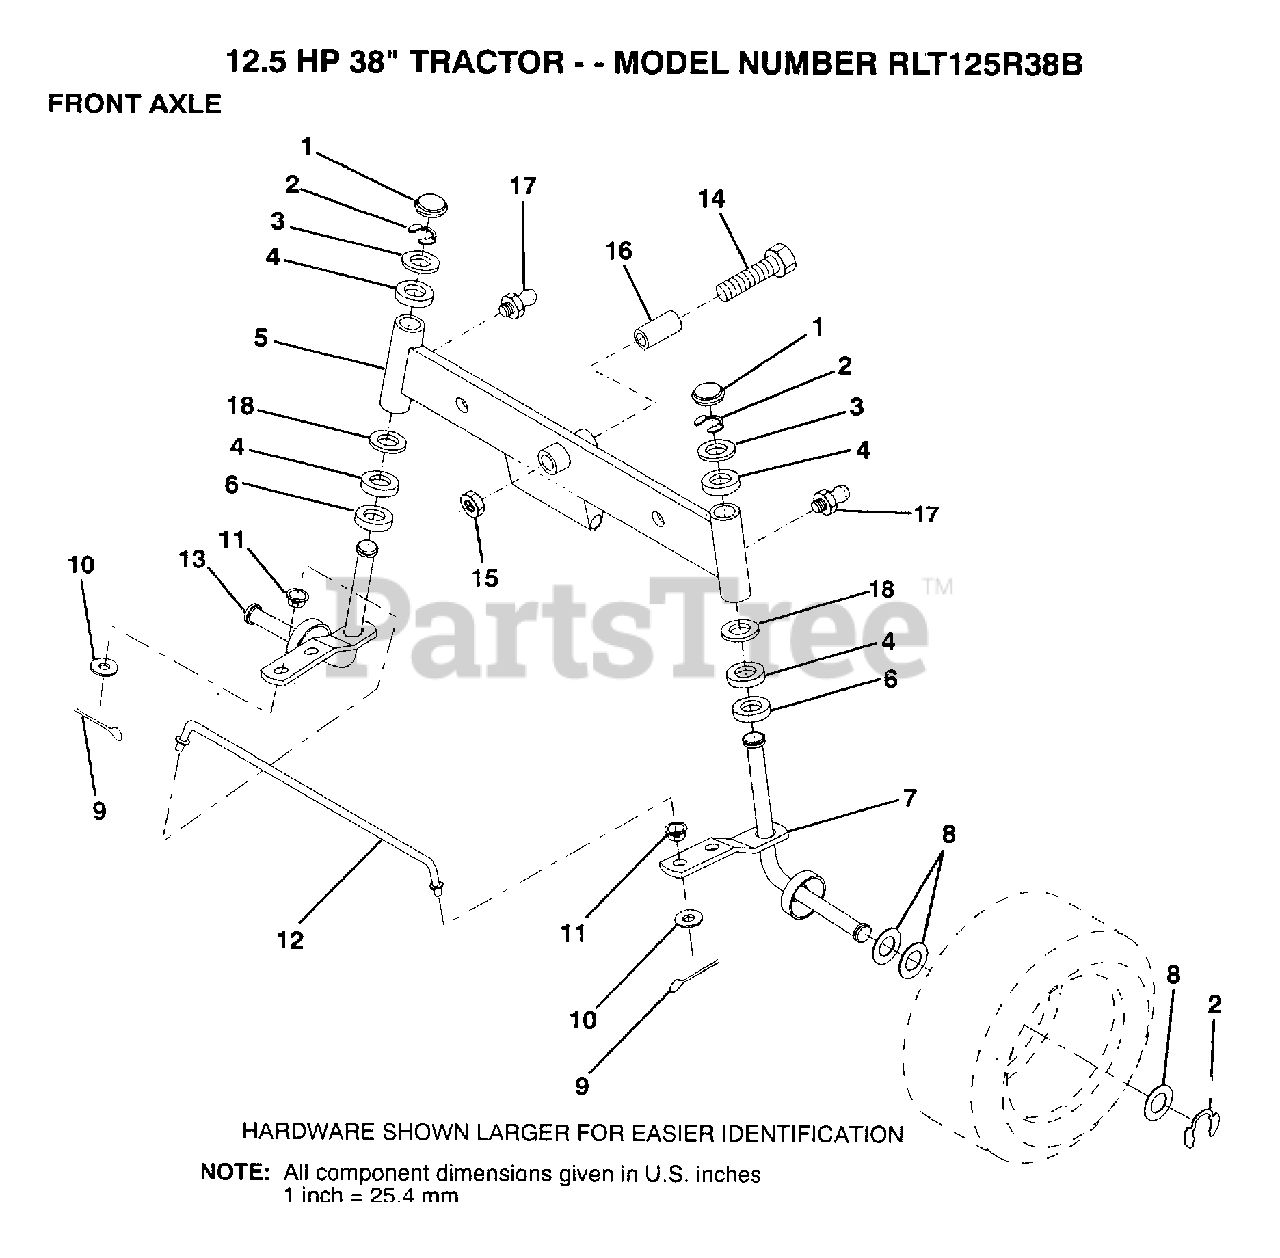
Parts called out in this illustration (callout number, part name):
1	CAP
2	RING
3	WASHER
4	COL. SRTG. BEAR.
6	WASHER .T
7	SPINDLE ASM RH
8	WASHER
9	COTTER PIN
10	WASHER
11	BUSHING.DRAGLINK
12	TIE ROD
13	SPINDLE ASM LH
14	BOLT HEX 5/8-11
16	BEARING
17	ZERK M
18	WASHER
